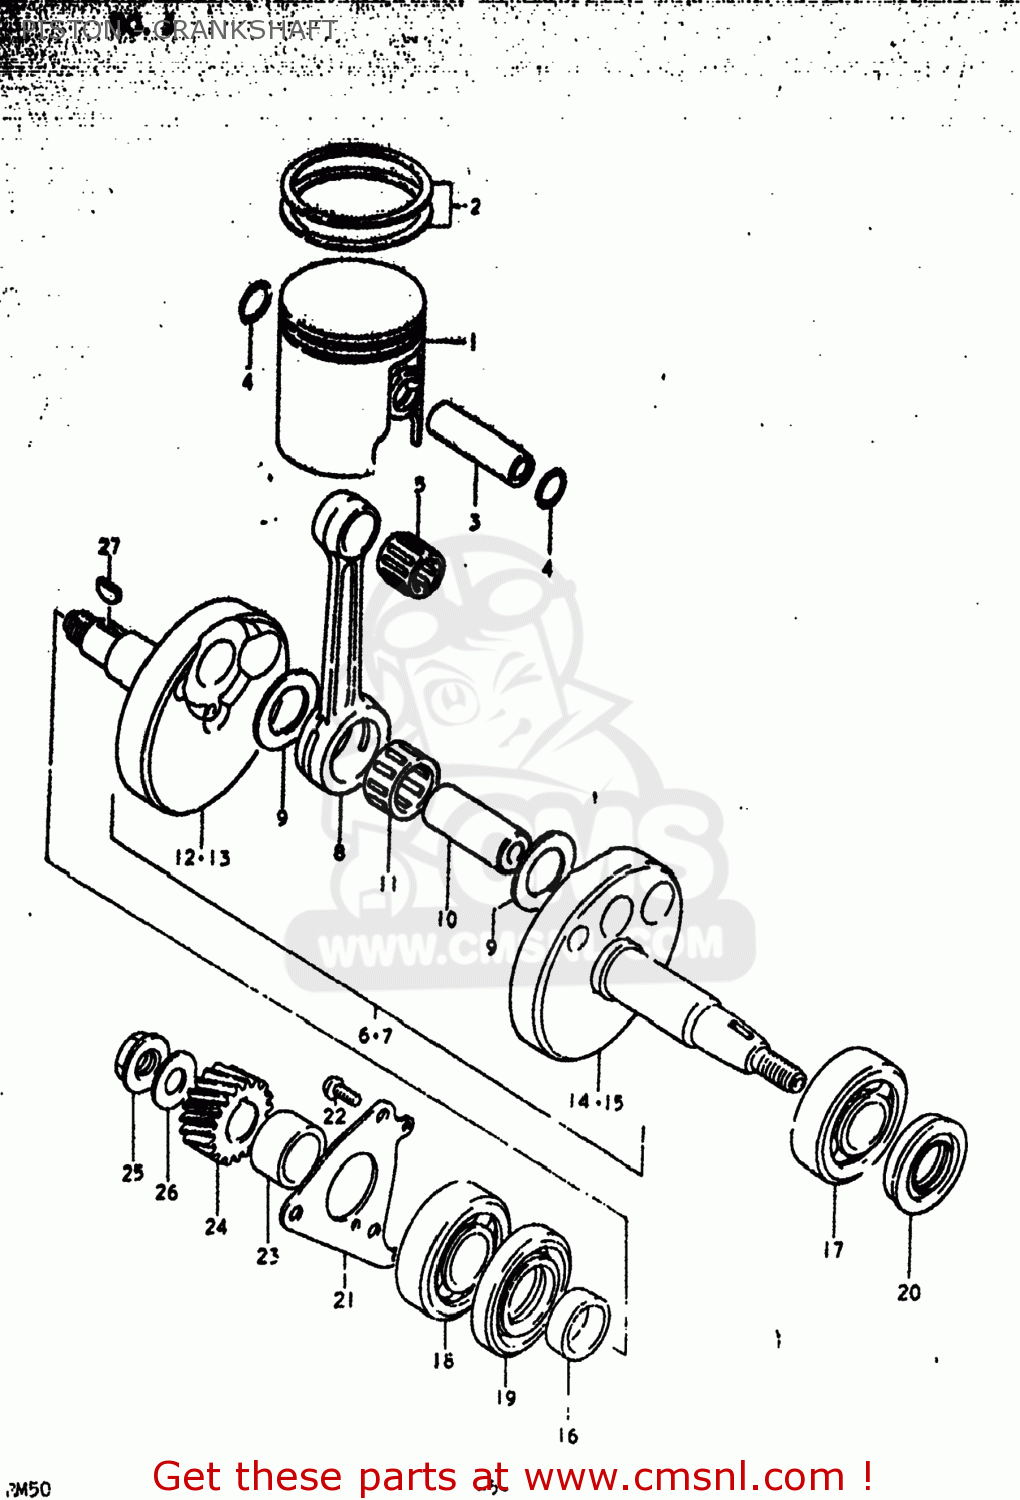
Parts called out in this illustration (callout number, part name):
1	PISTON
2	RING SET,PISTON
3	PIN,PISTON
4	RING,SNAP
5	BEARING
6	CRANKSHAFT ASSEMBLY
7	CRANKSHAFT ASSEMBLY
8	CONNECTING ROD
9	WASHER(16X29X1)
10	PIN,CRANK
11	BEARING
12	CRANKSHAFT,RIGHT
13	CRANKSHAFT
14	CRANKSHAFT,LEFT
15	CRANKSHAFT,LEFT
16	SPACER(20X26X9)
17	BEARING
18	BEARING
19	OIL SEAL
20	OIL SEAL
21	RETAINER,CRANKSHAFT BEARING,R
22	SCREW 6X12
23	SPACER(20X26X14)
24	GEAR,PRIMARY DRIVE NO.19
25	NUT
26	WASHER
27	KEY
